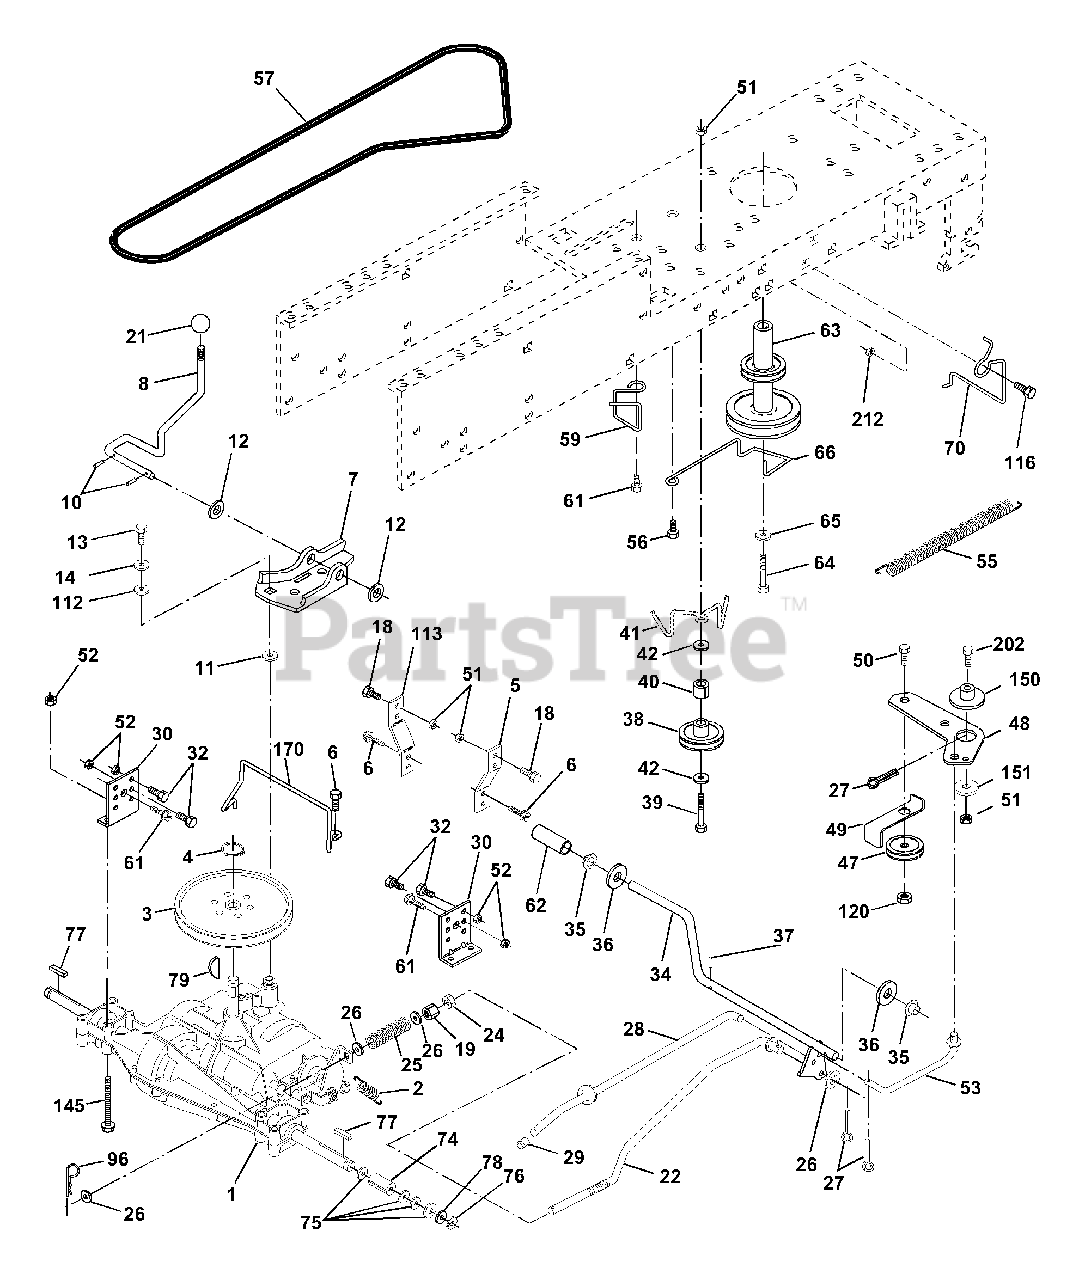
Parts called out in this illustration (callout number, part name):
2	Spring Return Brake T/a Zinc
3	Pulley Transaxle 18/20" tires
4	Ring Retainer # 5100-62
5	Strap Torque 30 Degrees
6	Screw 5/16-18 x 3/4
7	Bracket Saddle Shift T/a
8	Rod Shf Sdl LY/YT Str Blk
10	Pin Cotter 1/8 x 1 Cad
11	Washer Plate Shf
12	Washer 15/32 x 3/4 x 16ga
13	Bolt 1/4-28unf Gr8 W/Patch
14	Washer Lock Hvy Helical 1/4
18	Bolt Fin Hex 3/8-16 x 1 Gr.5
19	Nut Lock 3/8-16 Unc
21	Knob Rd 1/2-13 Plstc Thds
22	Rod Brake Blk Zinc 26 840
24	Nut Hex Jam 3/8-16 Unc
25	Spring Rod Brake 2 00 Zinc
26	Washer 13/32 x 13/16x16 Ga
27	Pin Cotter 1/8 x 3/4 Cad
28	Rod Brake Parking Lt/Yt
29	Cap Brake Parking
30	Bracket Mtg Transaxle
32	Bolt Fin Hex 5/16-18 x 3/4
34	Shaft Asm Pedal Foot Nibbed
35	Bearing Nylon Blk 629 Id
36	Washer 21/32 x 1 x 16 Ga
37	Pin Roll 3/16 x 1"
38	Pulley Composite Flat
39	Bolt Rdhd 3/8-16unc x 3 Gr.5
40	Spacer Split 395 x 59 Bzp
41	Keeper Belt Idler
42	Washer 13/32 x 13/16x12 Ga
47	Pulley Idler V Groove Plastic
48	Bellcrank Clutch Grn Drv Stl
49	Retainer Belt Style Spring
50	Bolt Hex Hd 3/8-16uncx1-1/2
51	Nut Crownlock 3/8-16 UNC
52	Nut Lock 5/16-18
53	Link Clutch 7 66
55	Spring Return Clutch 6 75
56	Screw 3/8-16 x 1
57	V-Belt Gd Drive
59	Keeper Belt Center Span
61	Screw 3/8-16 x 3/4
62	Cover Pedal Blk Round
63	Pulley Engine
64	Bolt Hex 7/16-20 x 4 Gr 5
65	Washer Lock Hvy Hlcl Spr 7/16
66	Keeper Belt Engine
70	Guide Belt Mower Drive RH
74	Spacer Axle
75	Washer 25/32 x1 1/4 x 16 Ga
76	E-ring #5133-75
77	Key Square 2 0 x 1845/ 1865
78	Washer 25/32 x 1-5/8 x 16ga
79	Key Woodruff #9 3/16 x 3/4
96	Retainer Spring
112	Washer 9/32 x 3/4 x 10 Ga
113	Strap Torque
116	Bolt Rdhd Sq Neck 3/8-16 x 1
120	Nut Lock 3/8-16
145	Bolt Hex Flghd 5/16-18 Gr. 5
150	Spacer Retainer
151	Washer 13/32 x 2 x 10 Ga
170	Keeper Belt Transaxle Gear
202	Bolt Carr Sh 3/8-16 x 1-3/4 Gr. 5
212	Nut Hex Flange Lock
